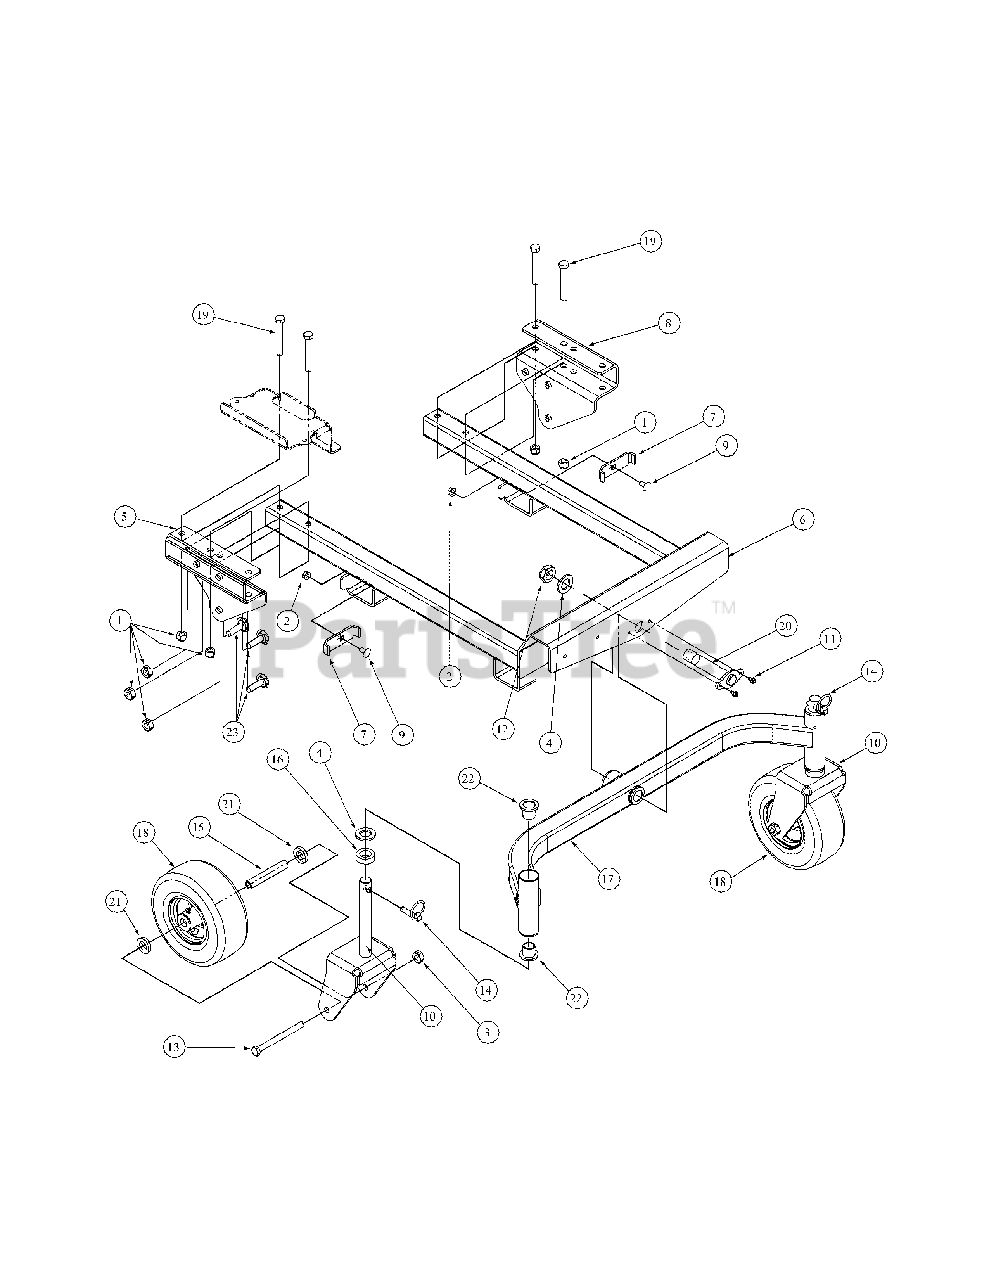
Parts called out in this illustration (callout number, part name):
1	Hex Jam Nut 1/2-13
2	Nut, Hex 3/8-16 Flange Lock
3	Nut, 1/2-20, Center Lock
4	Washer Special
5	Support Brack Frame Right Hand
6	Front Frame Assembly
7	Plate Wear
8	Bracket Support Frame, Left Hand
9	Carrige Bolt, 3/8-16 x .75 LG.
10	Caster Assembly
11	Screw, 1/4-20, 0.62,
12	Nut, Jam, 1.0-14, Insert Lock
13	HHCS, 1/2-20, 7.00"
14	Pin, Klik, 1.75 LG
15	Spacer Wheel
16	Spacer, 1.015 ID x 1.62 OD x .5
17	Front Axle Assembly
18	Wheel Assembly 11.0 x4.00 -5
19	Hex Cap Screw, 1/2-13 x 3.5
20	Pin Assembly, Plated
21	Spacer, .812 ID x .268 Lg
22	Flange Bearing, 1.013 ID
23	Carriage Bolt, 1/2-13 x 1-1/4
